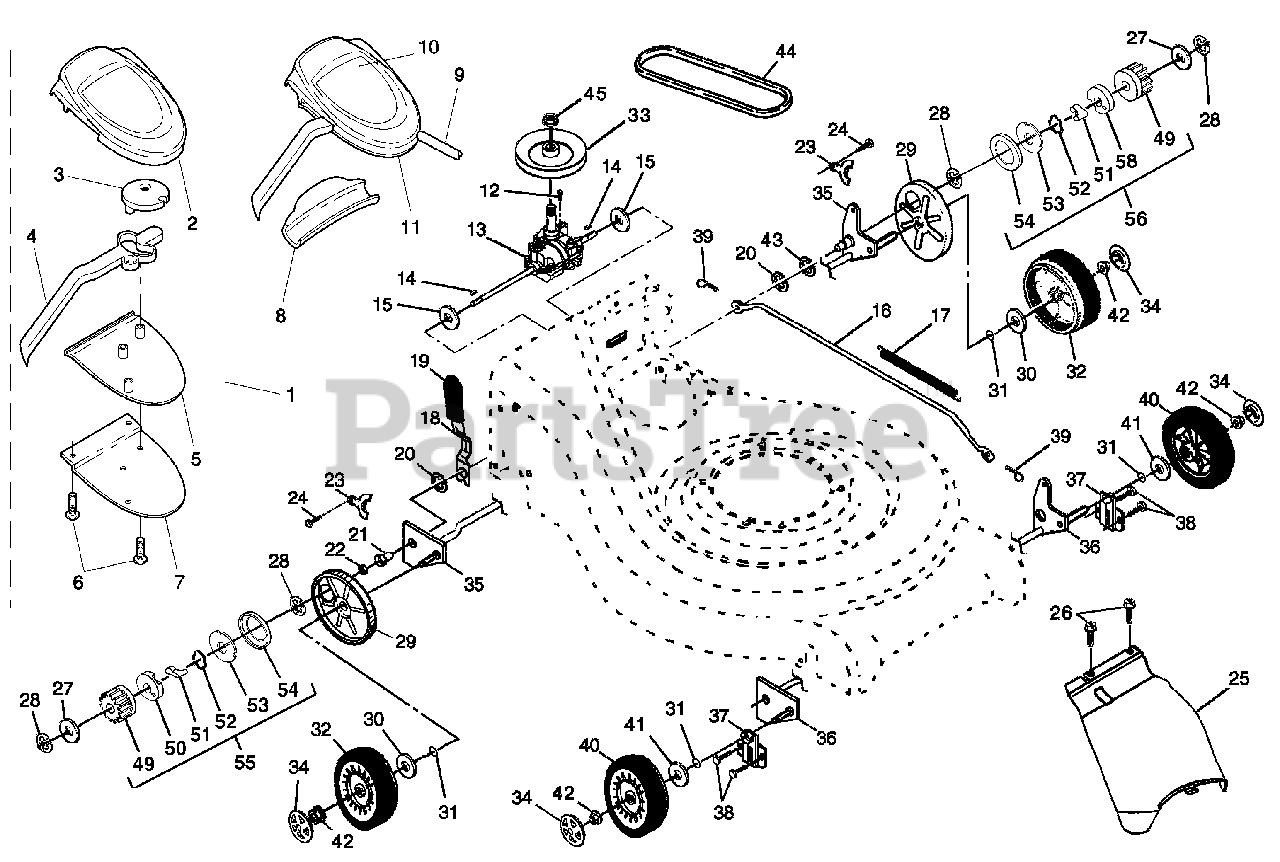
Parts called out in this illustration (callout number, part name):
1	Drive Control Assembly, Auto-Walk
2	Cover, Top, Auto-Walk Drive Control
4	Lever, Auto-Walk Drive Control
5	Cover, Bottom, Auto-Walk Drive Control
6	Screw, Phillips Head #10 x 5/8
7	Plate, Trigger, Auto-Walk Drive Control
8	Cap, Drive Control, Bottom
9	Cable, Drive Control
10	Decal, Drive Control
11	Decal, Drive Control Adjustment (bottom)
13	Gear Case Assembly
16	Rod, Connecting
17	Spring, Extension
18	Spring Selector
19	Knob, Selector Spring
21	Bearing, Support
22	Bearing, Ball
23	Retainer, Drive Assembly, Stamped
24	Screw, Tapping, Hex Head 1/4-20 x .75
25	Cover Drive
26	Screw, Threaded, Rolled #10-25 x .50
28	E-Ring 7/16
29	Cover, Dust, Wheel
30	Washer 1/2 x 1-1/2 x .134
31	O-Ring
32	Wheel 9 x 2
33	Pulley, Drive
34	Hubcap
35	Shaft Assembly, Rear
36	Shaft Assembly, Front
37	Retainer, Front Shaft
38	Screw #12 x 5/8
39	Clip, Retainer
40	Wheel 8 x 2
41	Washer, Flat 3/8
42	Nut, Hex, Flangelock 3/8-16
44	V-Belt
45	Nut, Hex, Flanglock, Zinc Plated 3/8-16
46	Decal, Drive Control
48	Decal, Drive Control Operation
49	Gear, Pinion
50	Retainer, Drive, RH
52	Spring, Torsion
53	Disc, Drive
54	Seal, Friction
55	Pinion Assembly, RH
56	Pinion Assembly, LH
58	Retainer, Drive, LH
